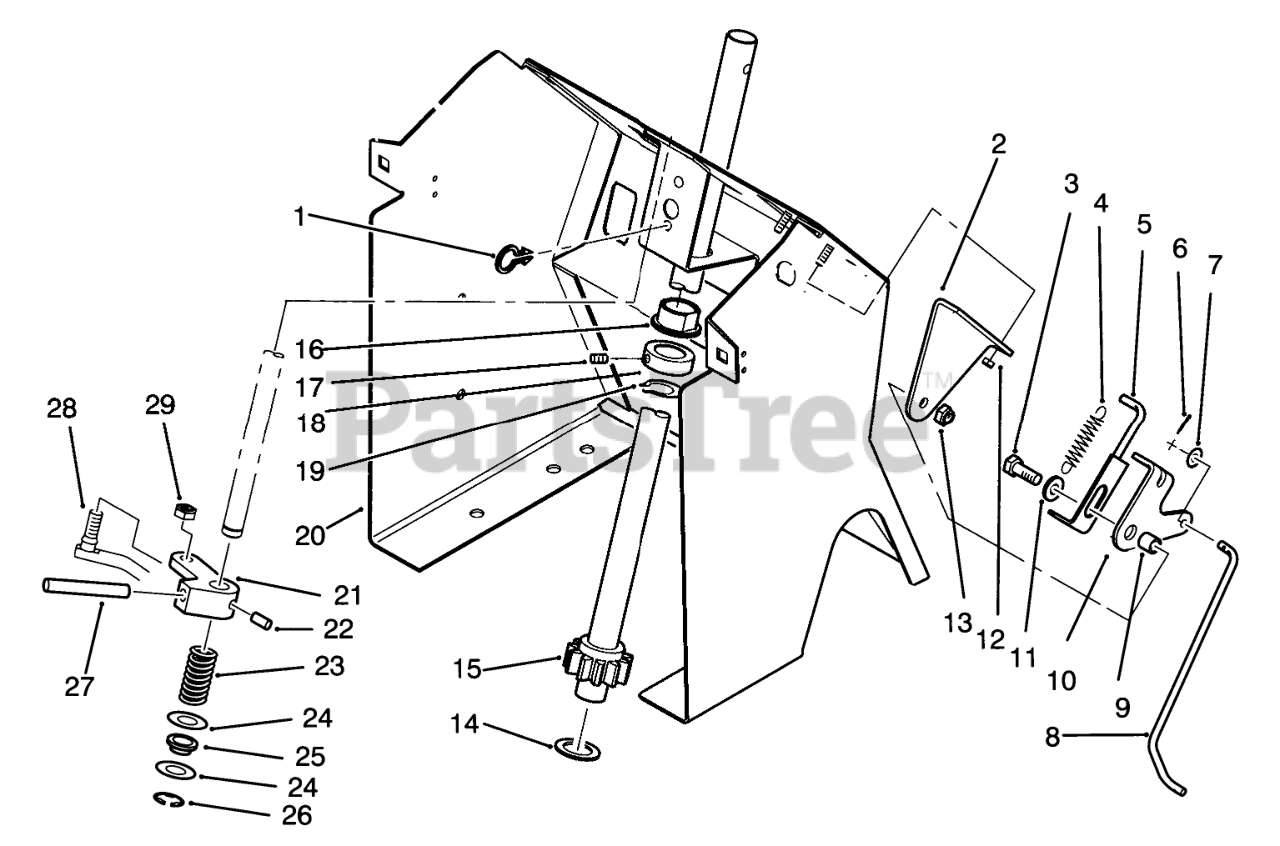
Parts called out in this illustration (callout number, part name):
1	CLIP-SNAP IN
2	SUPPORT-INDICATOR B
3	SCREW-HH
4	SPRING-EXTENSION
5	WLDMT-INDICATOR R
6	Cotter Pin
7	WASHER-FLAT
8	ROD-INDICATOR
9	SPACER
10	RETAINER-INDICATO B
11	WASHER-FLAT
12	Nut
13	NUT-LOCK, NI
14	WASHER
15	WLDMT-STRG SHAFT
16	COLLAR
17	SCREW-HSH
18	BEARING-FLANGED
19	RING-RETAINING
20	HOOD STAND W/A B
21	ARM-SPEED CONTROL
22	PIN-SPIROL
23	SPRING-COMPRESSION
24	SHIM-WASHER
25	BUSHING-NYLINER
26	RING-SHAFT, EXT
27	PIN-SPIROL 5/16X2.25
28	ROD-SHIFT R
29	NUT-LOCK, NI
